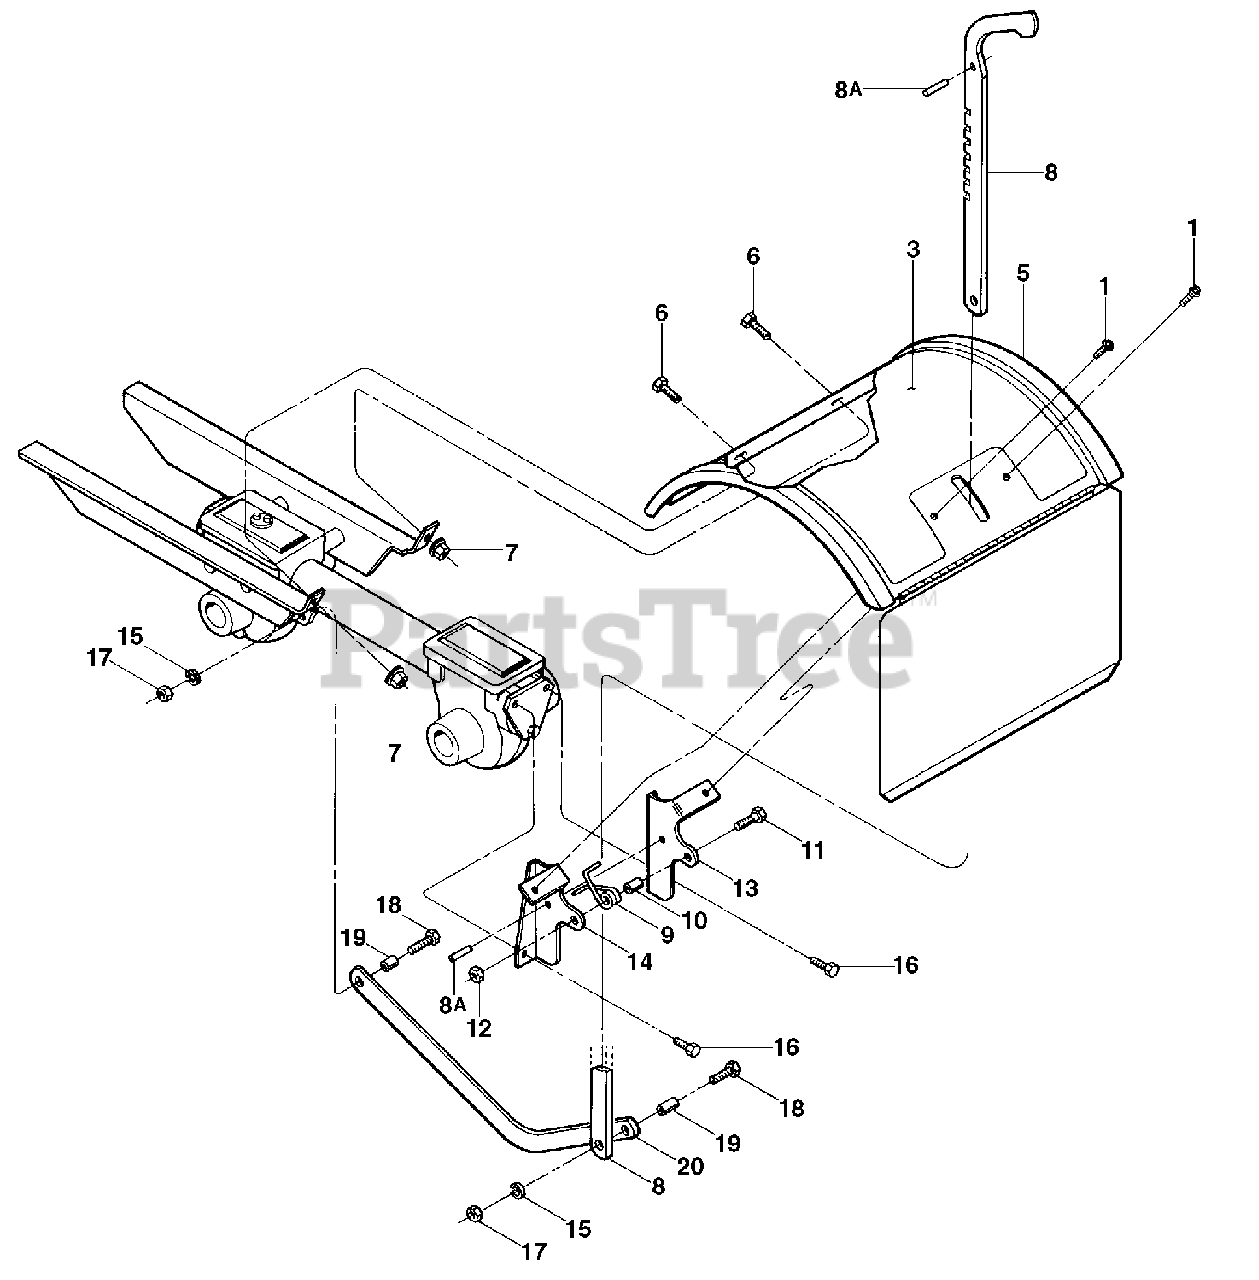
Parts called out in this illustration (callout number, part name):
1	Hex Hd. Flange Screw, Self-Tapping, 1/4-20 x 1/2
3	Decal, Hood
5	Tine Hood
6	Hex Hd. Screw, 5/16-18 x 1/2
7	Hex Flange Lock Nut, 5/16-18
8	Depth Regulator Lever
8A	Spirol Pin
9	Spring, Depth Regulator
11	Hex Hd. Screw, 1/4-20 x 1
12	Hex Lock Nut, 1/4-20
13	Hood Bracket, Right Hand
14	Hood Bracket, Left Hand
15	Lock washer, 5/16
16	Hex Hd. Flange Screw, 5/16-18 x 1
17	Hex Nut, 5/16-18
18	Hex Hd. Screw, 5/16-18 x 1-1/4
20	Drag Bar
